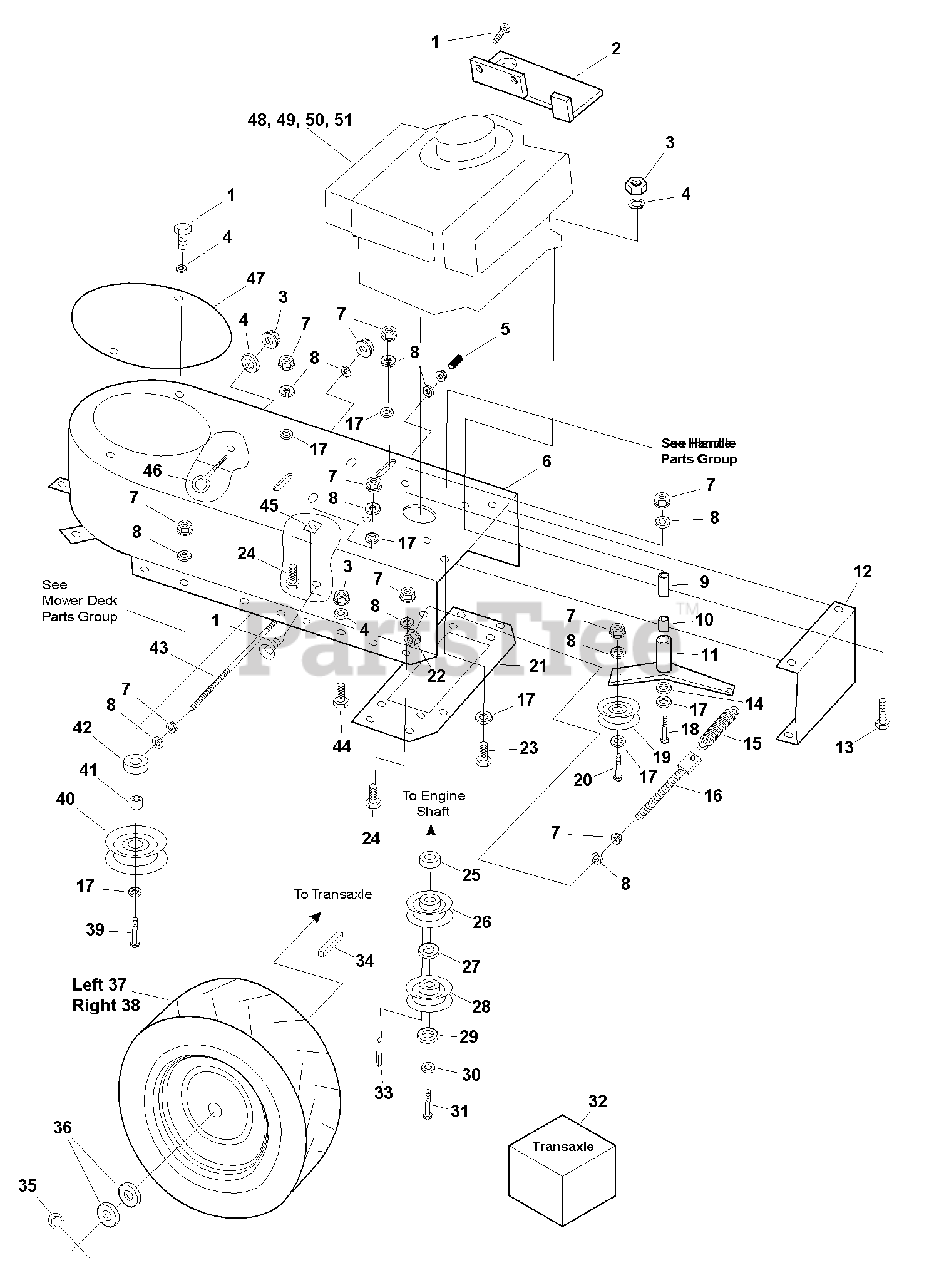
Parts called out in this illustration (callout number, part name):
1	Capscrew, TapTite Hex Head, 5/16-18 x 3/4
2	Auxiliary fuel tank base
3	Nut, Hex, 5/16-18
4	Lockwasher, 5/16
6	Engine Deck (S/N 071601076 & Up)
6	Engine Deck (S/N 071601075 & Below)
7	Nut, Hex, 3/8-16
8	Lockwasher, 3/8
9	Idler Arm Pivot Boss
10	Sleeve Bushing, 3/4 ID
11	Transmission Idler Arm
12	Engine deck back cover
13	Capscrew, 5/16-18 x 1-1/2
14	Flatwasher, 1/2
15	Idler Spring
16	Idler Tension Rod
17	Flatwasher, 3/8
18	Capscrew, 3/8-16 x 3-1/4
19	Idler Pulley
20	CAPSCREW, Hex Head, 3/8-16 x 1-3/4
21	Lower handle mounting plate
22	Nut, Hex 3/8-16
23	Capscrew, 3/8-16 x 1-1/4
24	Capscrew, Hex Head, 3/8-16 x 1
25	Engine Shaft Spacer, 7/8"
26	Blade Clutch Drive Pulley
27	Spacer, 1/8"
28	Transmission Drive Pulley
29	Flatwasher Heavy Duty, 7/16
30	Lockwasher, 7/16
31	Capscrew, Socket Head, 7/16-20 x 1-1/2
33	Key, Engine Shaft, 1/4 x 1/4 x 2-1/8
34	Key, Axle Shaft 3/16 x 3/16 x 1-3/8
36	Washer
37	Drive Wheek, Left
39	Capscrew, Hex Head, 3/8-16 x 3-1/4
40	Blade clutch idler pulley
41	Idler pulley spacer bushing
42	Blade Clutch Idler Boss
43	Blade Clutch Idler Tensioning Rod
44	Capscrew, 5/16-18 x 2-1/4
45	Transmission Forward Mounting Hanger
46	Eyebolt, 5/16-18x3-1/4
47	Clutch Cover Plate
48	Engine - 13.5 HP Briggs & Stratton
49	Engine - 13 HP Honda
50	Engine - 15 HP Kawasaki
51	ENGINE, 16 HP Briggs & Stratton
